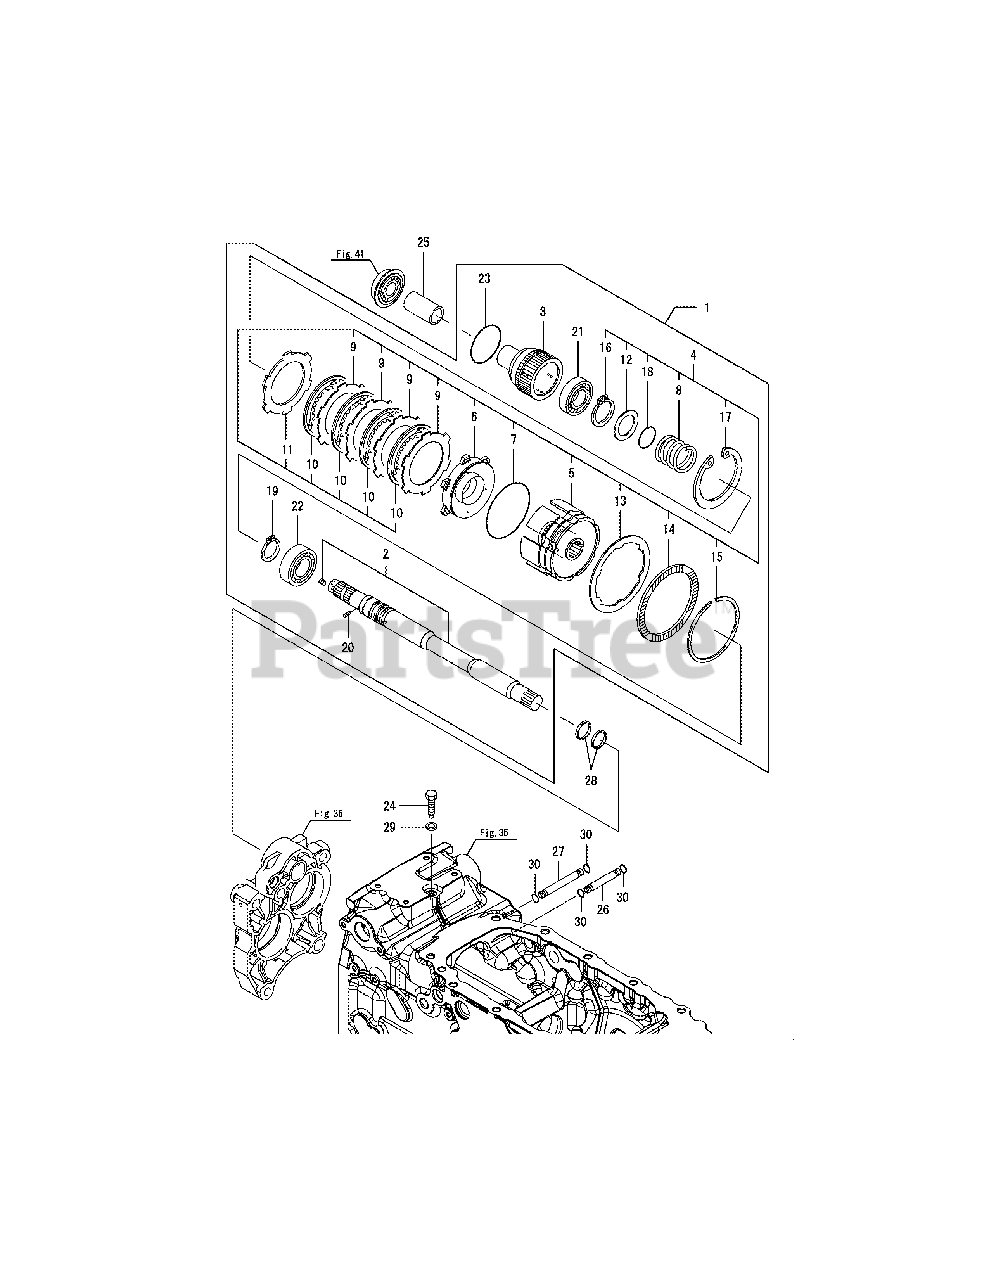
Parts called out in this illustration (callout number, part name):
1	CLUTCH,PTO KIT
2	SHAFT ASSY, CLUTCH
3	HUB, SPLINE PTO
4	CLUTCH CMP(PTO
5	CASE, CLUTCH(PTO
6	PISTON, HYDRAULIC
9	PLATE,SEPARATE
10	DISC,CLUTCH 2.0
11	PLATE,BACK 3.2
17	CIRCLIP 100(H)
18	O-RING 1A S-32.0
20	SPRING PIN 3X 8
21	BALL BEARING #6204
23	O-RING 1A G-60.0
24	BOLT M10, STOPPER
28	RING 262730073,SEAL
29	GASKET 10, ROUND
30	O-RING, 1A S8.0
